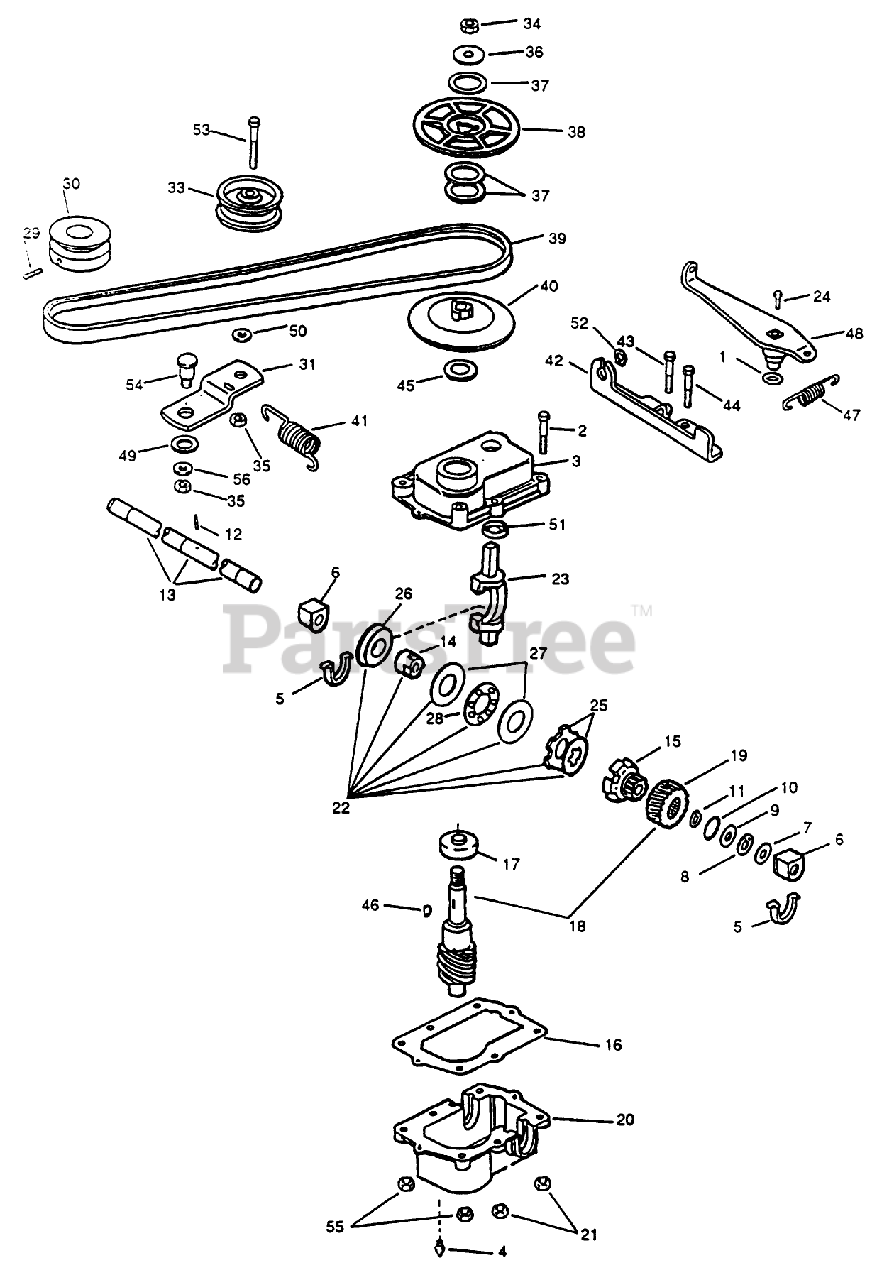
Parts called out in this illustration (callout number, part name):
1	O-RING
6	BEARING & SEAL AY (12)
7	THRUST WASHER
9	WASHER-THRUST
11	RET RING
12	PIN DRIVE LOCK
13	SHAFT - DRIVE
15	DRIVER BROCKWAY
16	GASKET HOOSIER
17	BEARING-BALL
19	WORM WHEEL
21	LOCKNUT E
23	FORK SHIFT
24	SCREW SEMS SM
25	Disc Plate Kit
26	Collar
29	SET SCREW F
30	PULLEY F
33	PULLEY IDLER NHI
34	NUT-JAM, LOCKING
35	LOCKNUT
36	WASHER
38	PULLEY UPPER PL
39	V-BELT F
40	PULLEY LOWER PL
41	SPRING-EXT.
45	WASHER
46	KEY GALGER
47	SPRING
50	WASHER S
51	GUIDE ELCO
52	RET. RING
55	LOCKNUT E
56	WASHER
